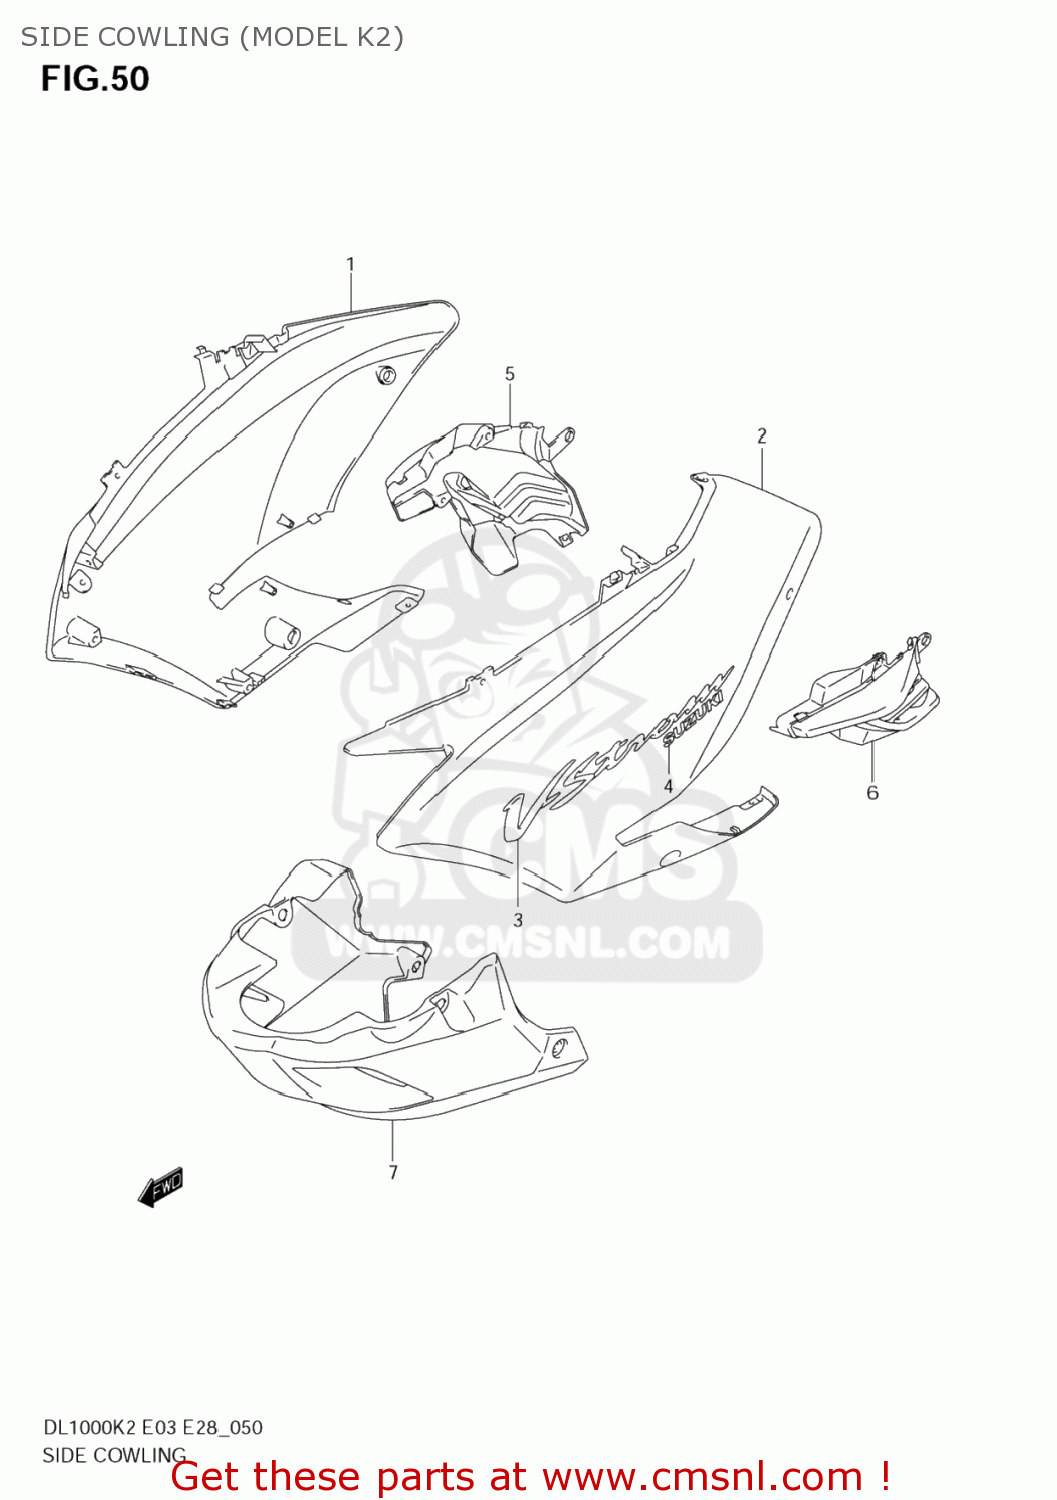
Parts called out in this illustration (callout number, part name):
1	COWLING ASSY,SIDE,R
2	COWLING ASSY,SIDE,L
3	EMBLEM,COWLING SIDE
4	EMBLEM,SUZUKI
5	COVER,SIDE COWL,R
6	COVER,SIDE COWL,L(GRAY)
7	COWLING,UNDER
